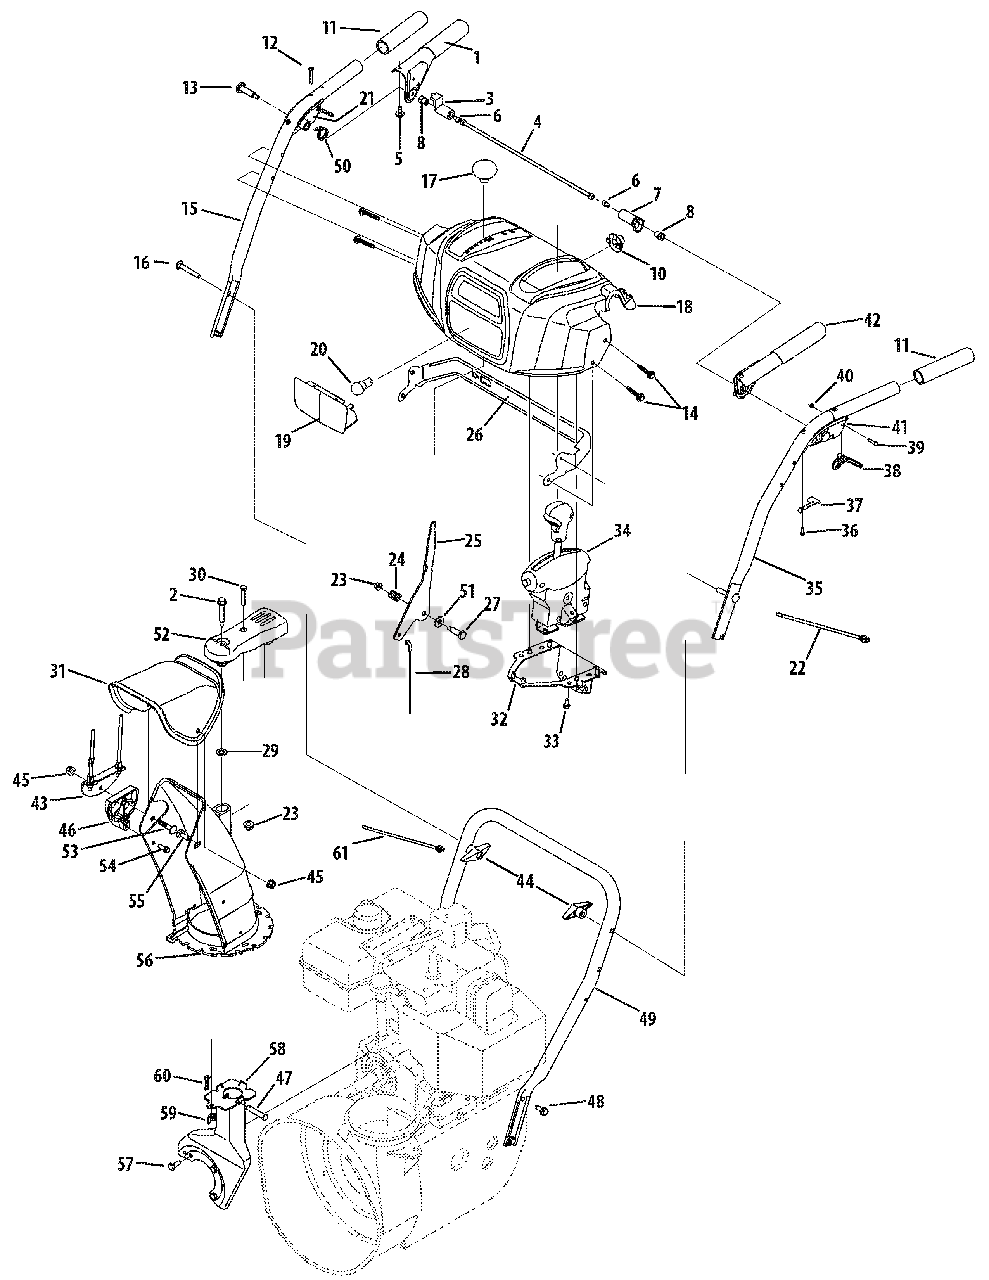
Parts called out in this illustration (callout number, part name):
1	Handle Engagement Assembly RH
2	Flange Shoulder Screw
3	Lock Plate
5	Rubber Bumper
6	Screw, 1/4-20 x.375
7	Clutch Lock Cam
8	Shoulder Nut, 1/4-20
10	Light Socket
11	Handle Grip
12	Screw, #10-24 x 0.375
13	Shoulder Screw, 1/4-20 x 1.345
14	Screw, 1/4-20 x 1.625
16	Carriage Screw, 5/16-18 x 2.25
17	Shift Knob
18	Handle Panel (Includes Ref. #19)
20	Lamp
21	Handle Clutch Lock RH Assy
22	Cable Tie
23	Flange Lock Nut, 1/4-20
24	Compression Spring
27	Shoulder Screw
28	Speed Selector Cable
29	Flat Washer, .25 x .630 x .0515
30	Hex Screw, 1/4-20 x 1.50
31	Upper Chute
33	Hi-Lo Screw, 1/4-15 x 0.5
34	4-Way Chute Control (™) Assembly
36	Screw, #8-16 x 0.50
37	Clutch Lock Spring
38	Steering Control
41	Handle Clutch Lock LH Assy
42	Handle Engagement Assembly LH
44	Wing Knob
45	Flange Lock Nut, 5/16-18
46	Chute Tilt Cable Guide
50	Torsion Spring
51	Flat Washer
52	Joystick Pulley Cover
53	Carriage Bolt, 5/16-18 x 1.50
54	Hi-Lo Screw, 1/4-15 x .75
55	Carriage Bolt, 5/16-18 x 1.0
56	Lower Chute
57	Hex Screw, 5/16-24 x .750
60	Bow Tie Cotter Pin
61	Cable Tie
